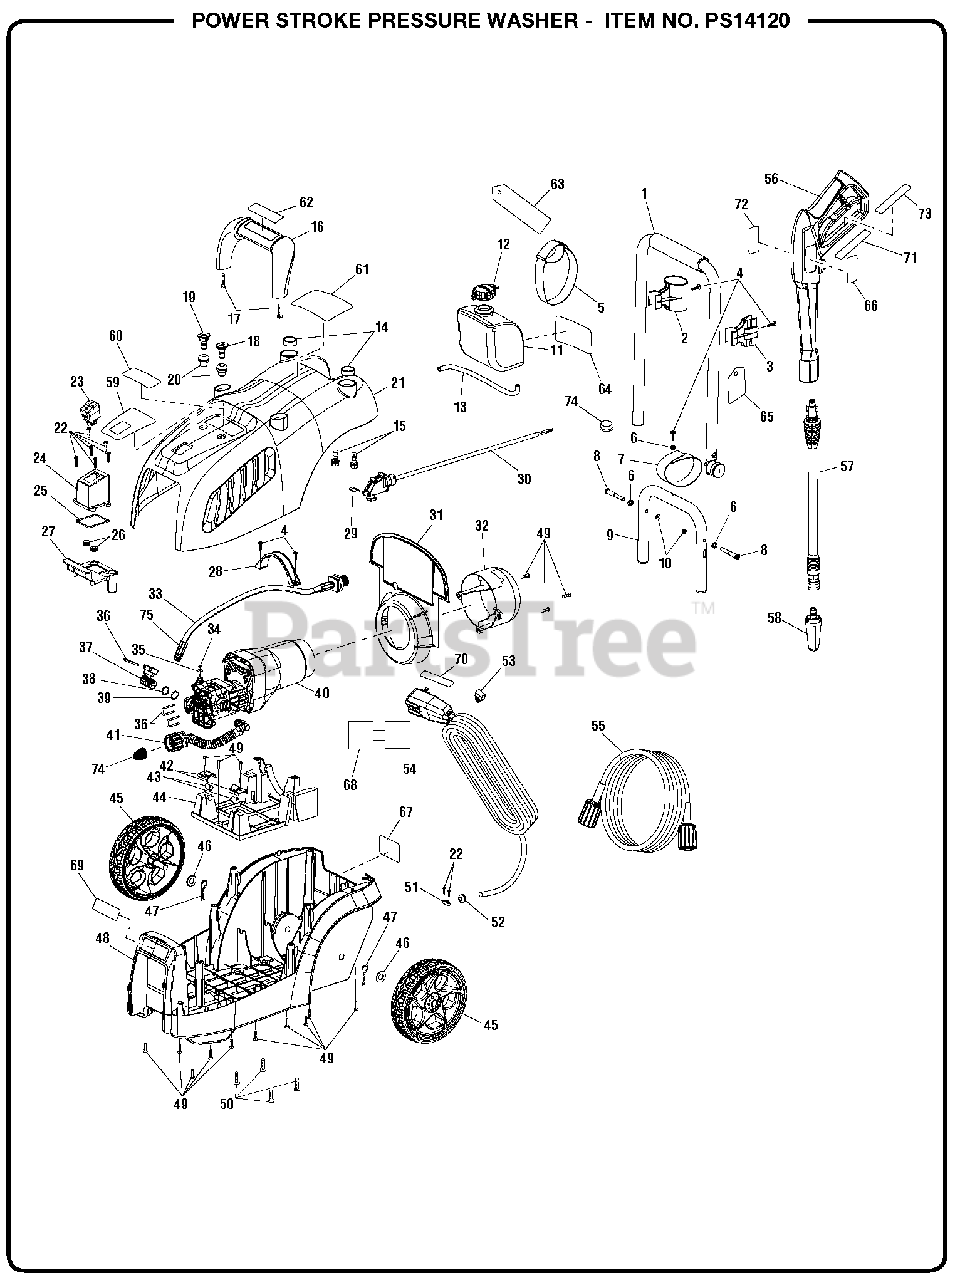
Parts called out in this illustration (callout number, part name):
1	Handle Assembly
2	Trigger Handle Holder
3	Wand Holder
4	Screw (M4.2 x 16 mm)
5	Velcro Strap (For Hose)
6	Washer (ID 8 x OD12t x 2.5t)
7	Velcro Strap (For Power Cord)
8	Shoulder Bolt (M6 x 52.5 mm)
9	Lower Handle
11	Soap Tank
12	Soap Tank Cap
13	Chemical Siphon Tube
14	Lower Handle Ring
15	Bolt (M8 x 20 mm)
16	Assist Handle
17	Screw (M5.5 x 30 mm)
18	Soap Nozzle (Blue)
19	15deg Nozzle
20	Nozzle Grommet
21	Upper Housing
22	Screw (M3.5 x 16 mm)
24	Switch Box
25	Switch Seat Gasket
27	Switch Bracket
28	Motor Strap
30	Switch Assembly (Total Stop Switch)
31	Heat Shield
32	Air Funnel
33	Water Outlet Assembly
34	O-Ring
35	Washer (Brass)
37	Outlet Connector
38	Backup Ring
40	Pump and Motor Assembly
41	Water Inlet Hose Assembly
42	Clamp plate
43	Shock Absorber
44	Motor Support Board
45	Wheel Assembly
47	Cotter Pin
48	Lower Housing
49	Screw (M4.2 x 16 mm)
50	Screw (M5.5 x 20 mm)
51	Cord Clamp
52	Grommet (Housing)
53	Cord Clip
54	Power Cord
55	High Pressure Hose
56	Trigger Handle
57	Spray Wand
58	Turbo Nozzle
59	Performance Label
60	Nozzle Selection Guide
61	Warning Label (Fr/Sp)
62	Handle Logo Label
63	Warning Hangtag
64	Quick Start Label
65	Nozzle Hang Tag
66	Warning Label (Eng)
67	Data Label
68	Warning Label (Cord Wrap)
69	Logo Label
70	Power Cord Label
71	Trigger Handle Warning Label
72	Logo Label (Spray Wand)
73	Trigger Handle Rating Label
74	Handle Foot Cap
75	Inlet Filter
76	Outlet Connector Nut
